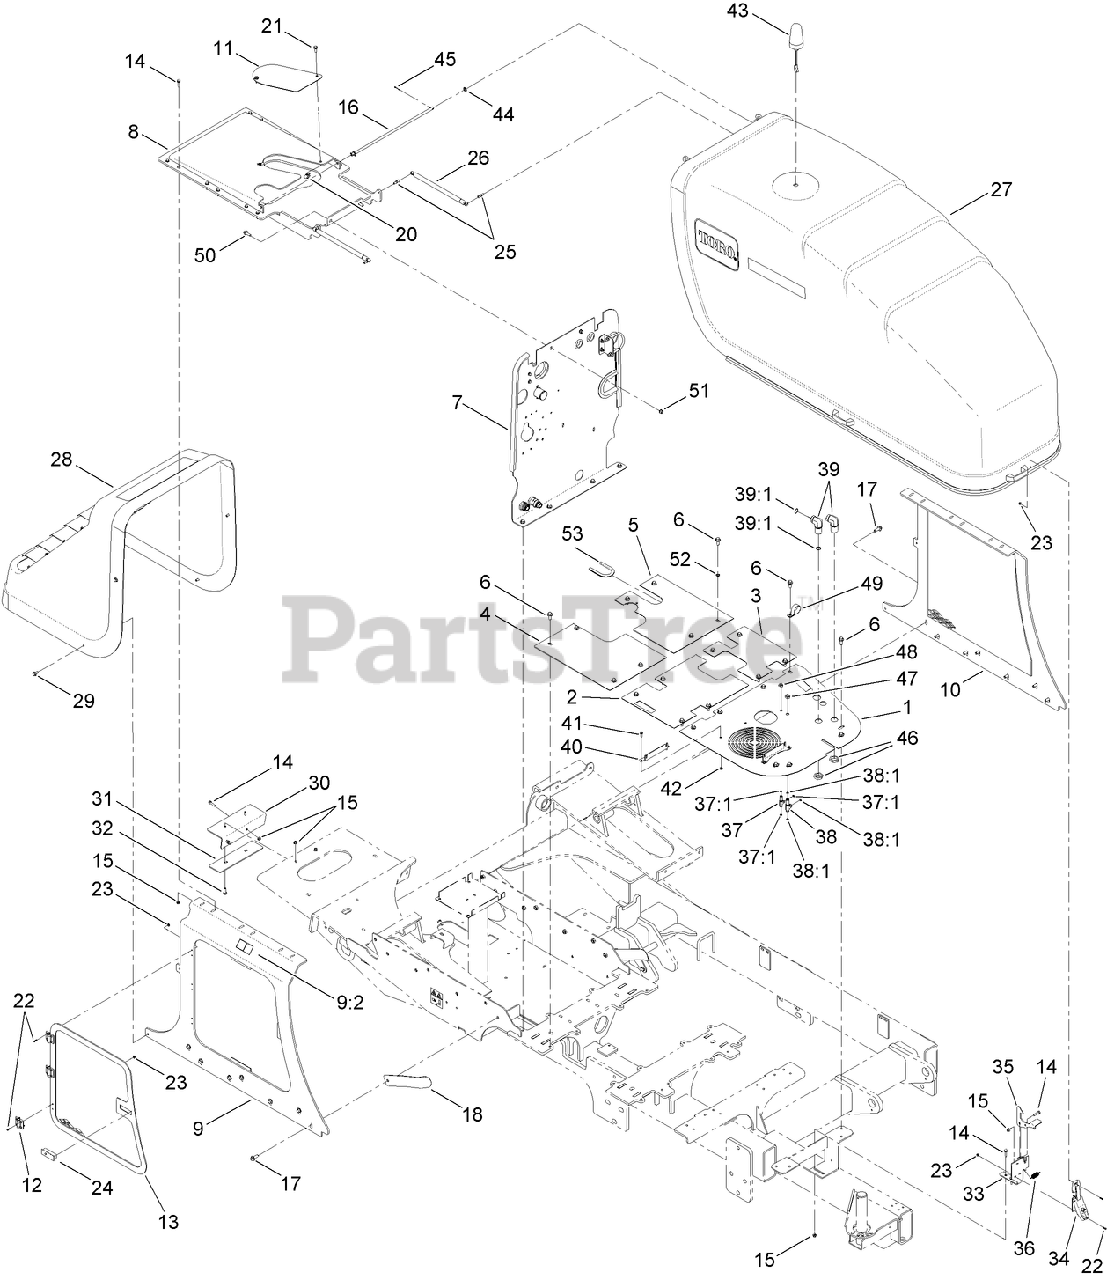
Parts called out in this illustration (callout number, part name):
1	PLATE-BULKHEAD
2	PLATE-SEAL, HOOD
3	PLATE-SEAL, HOOD
4	PLATE-HOOD SEAL
5	PLATE-HOOD SEAL
6	SCREW-HHF
7	BULKHEAD ASM
8	MOUNTING-HOOD
9	HOOD MOUNTING ASM
9:2	DECAL-WARNING, HOT SURFACE
10	MOUNT-HOOD
11	PLATE-COVER
13	DOOR-SIDE
14	SCREW-HHF
15	NUT-LOCK, HHF
16	PIN-MOUNT, HOOD
17	SCREW-HHF
18	GUIDE-HOOD
21	SCREW-HHF
22	SCREW-PRH
23	NUT-KEPS
24	LATCH-TRIGGER, RAISED (W/LOCK)
25	STUD-BALL
26	SPRING-GAS
27	FRONT HOOD ASM
28	REAR HOOD ASM
29	SCREW-HHF
30	PLATE-STOP, REAR HOOD
31	PLATE-SANDWICH, HOOD STOP
32	SCREW-HHF
33	MOUNT-HOOD, SAFETY LATCH
34	LATCH-DRAW, LOCKABLE
35	HOOK-HOOD, SAFETY LATCH
36	SPRING-TENSION
37	FITTING-TEE
37:1	O-RING
38	FITTING-TEE, BULKHEAD
38:1	O-RING
39	FITTING-ELBOW, 90
39:1	O-RING
40	PLATE-MOUNT, FAN
41	SCREW-HHF
42	NUT-FLANGE, NI
43	LIGHT-STROBE
44	WASHER-THRUST
45	PIN-COTTER
46	NUT-BULKHEAD
47	NUT-LOCK
48	NUT-LOCK
49	CLAMP-R
50	SCREW-HHF
51	NUT-LOCK, NI
52	WASHER-LOCK, EXT
53	TRIM-TANK
